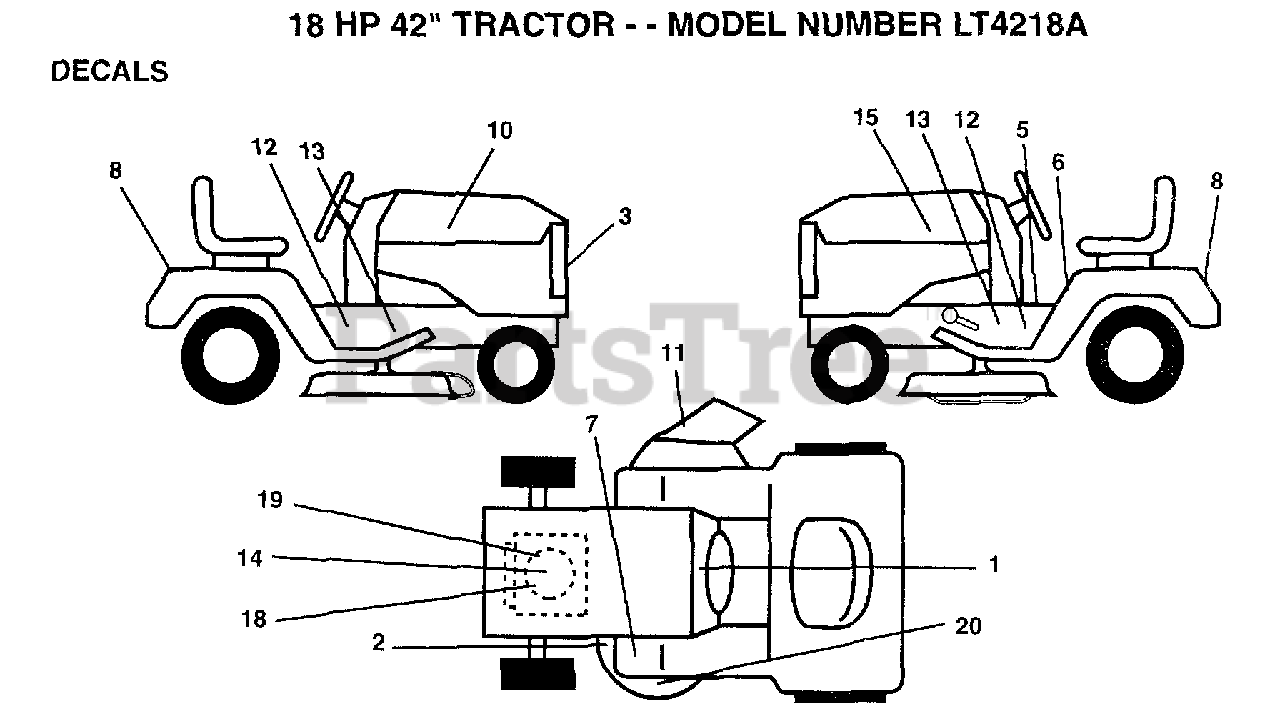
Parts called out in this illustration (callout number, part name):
1	DECAL INST OP DAS
2	DECAL.V.BELT
3	DECAL LOGO GRILLE
5	DECAL BRAK PARK
6	DECAL CAUT FEND
7	DECAL CLUT/BRAKE
8	DECAL FEND QUICK
10	DECAL HD RH
11	DECAL DANGER CT/F
12	DECAL CHASSIS KGR
14	DECAL.ENG.272757
15	DECAL HD LH
18	DECAL.ENG.272101
20	DECAL DECK MULCH
